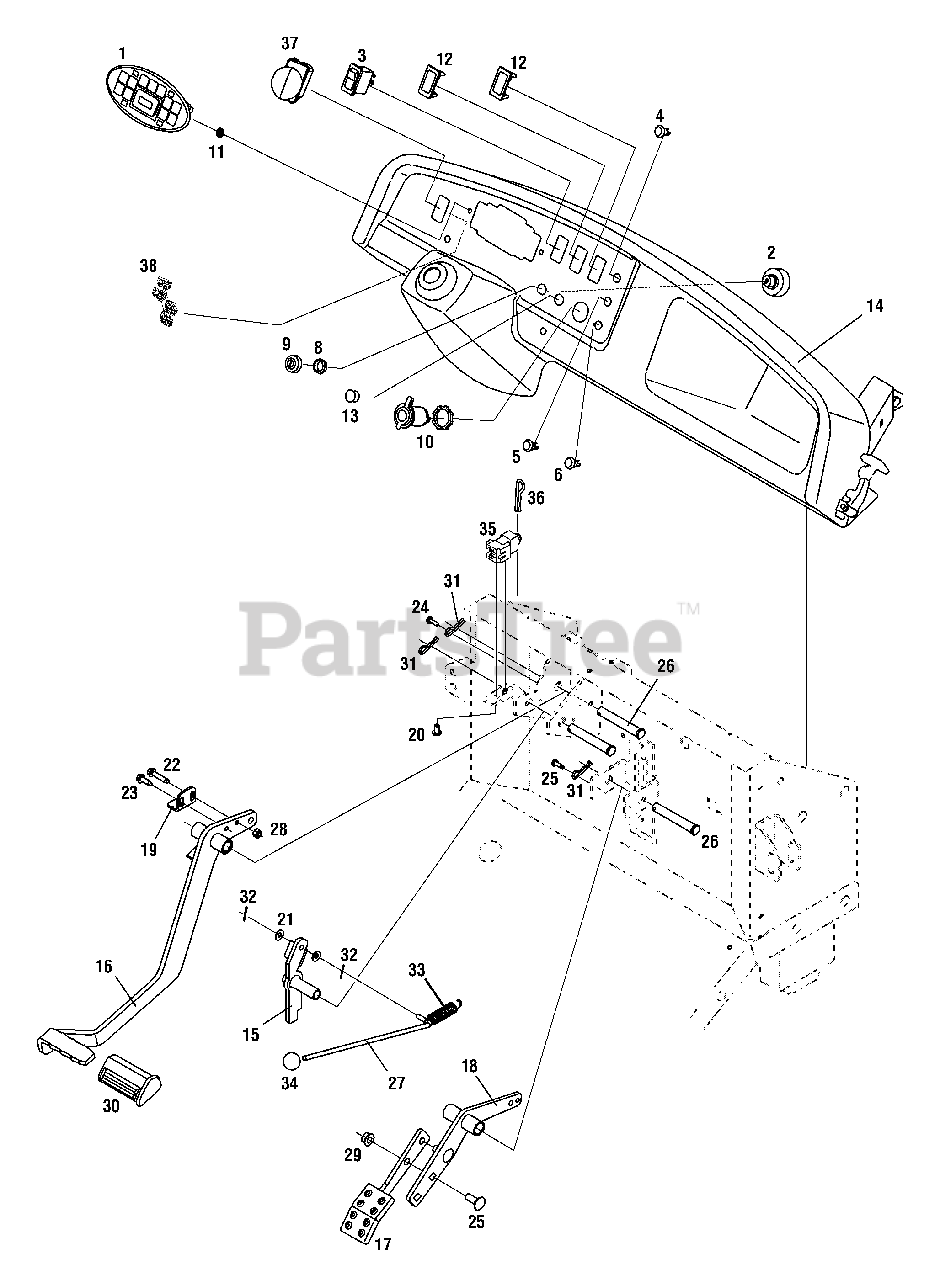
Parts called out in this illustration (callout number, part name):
1	Instrument Panel
2	Switch, Key
3	Rocker Switch
4	Switch, Green
5	Switch, Yellow
6	Switch, Red
7	Accessory Harness, Diff Lock
8	Nut, Ignition Switch, 5/8-32
9	Cap, Ignition Switch
10	Power Receptacle, 12V
11	Nut, Retainer, 1/8
13	Plug, Horn Switch
14	Dash Panel
15	Lever , Parking Brake
16	Pedal Assembly, Brake
17	Pedal Assembly, Throttle
18	Pedal Arm Assembly, Throttle
19	Plate, Brake Switch
20	Screw, Hi-Lo, 1/4-20 x .5
21	Washer, Flat .25 x .630 x .0515
22	Screw, Self-Tapping, 1/4-20x1.25
23	Screw, Self-tapping, 1/4-20, .75
24	Screw, Self-tapping, #10-32 x .625
25	Bolt, Carriage, 3/8-16 x 1.0
26	Pin, Clevis .50 x 3.25
27	Rod, Brake Lock
28	Nut, Hexlock, 1/4-20 GR 8
29	Nut, Flange Lock, 3/8-16
30	Pad, Brake Pedal
31	Pin, Cotter, .125 x 1.75
32	Pin, Cotter, 1/16
33	Spring, Extension, .637 x 2.972
34	Knob, Ball
35	Snap Mount Switch, Interlock
36	Pin, Cotter.08 x 1.42
37	Differential Lock Switch
38	Diff. Lock Accessory Harness Adapter
